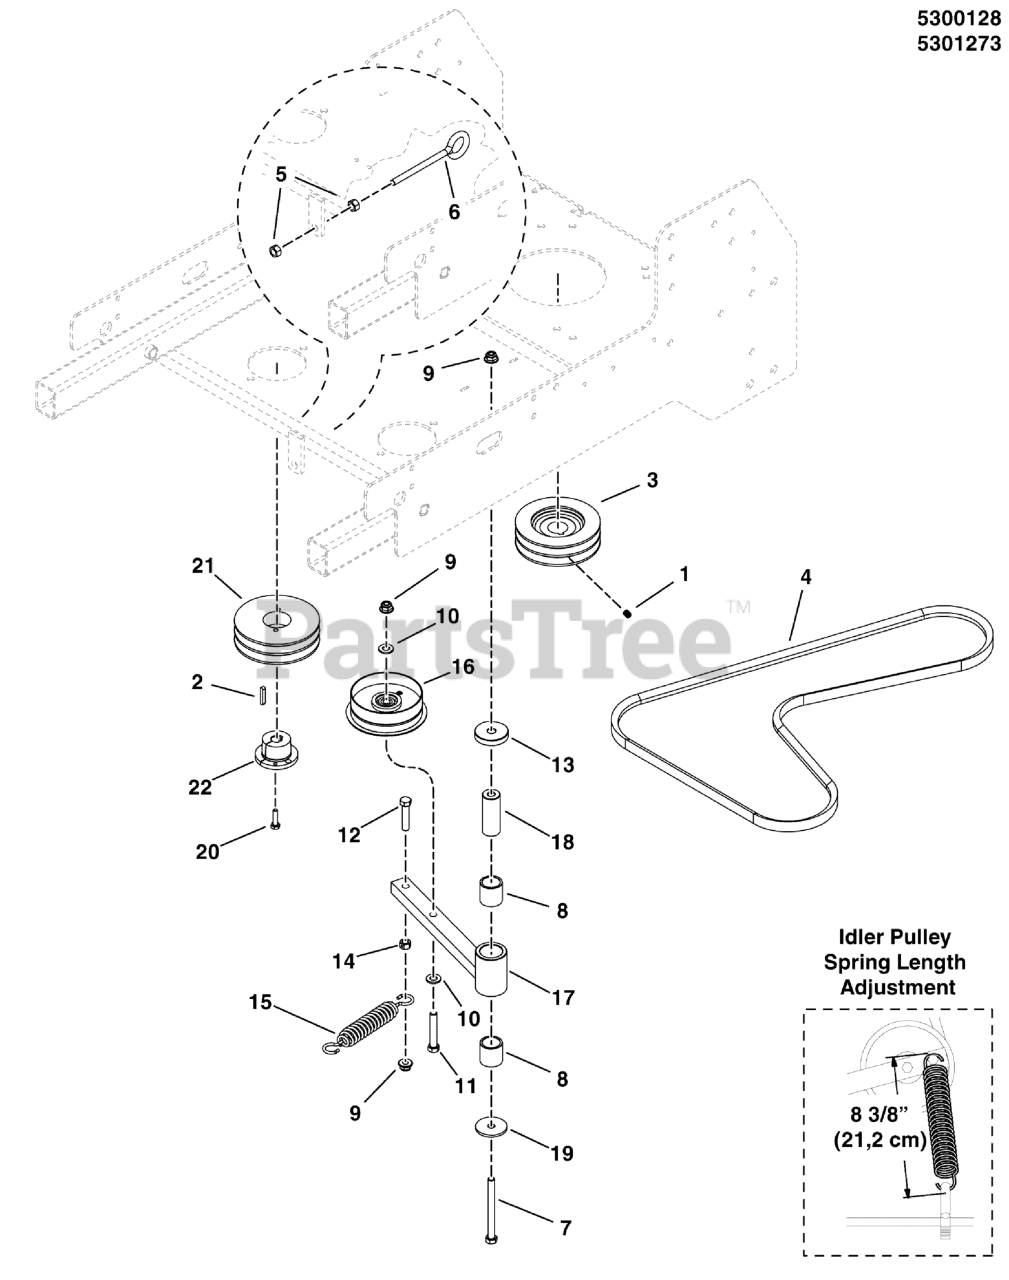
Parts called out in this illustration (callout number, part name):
1	SET SCREW, 5/16-18 X 3/8, KNURL, W/PATCH
2	KEY, 5MM SQ. W/ RADIUS
3	CRANKSHAFT PULLEY
4	BELT, BANDED A-SEC,64.76EL,POLY,RAW EDGE
5	NUT, 3/8-16 HEX
6	EYE BOLT, 3/8-16 X 6, 3.0 THREAD
7	BOLT, 3/8-16 X 4" GD5 CZ
8	BUSHING, BRASS, 1.25X1X1.25
9	NUT, 3/8-16 HEX NYLOCK FLANGE
10	WASHER, 3/8 GD.9 FLAT
11	BOLT, 3/8-16 X 2-1/4" GD5 CZ
12	BOLT, 3/8-16 X 1-3/4" GD5 CZ
13	SPACER, .45 X 1.88 X .38
14	NUT, 3/8-16 HEX SIDE LOCK
15	SPRING-EXT, 1.04 ODX6.935LGX.148WR, BLK
16	PULLEY, IDLER, SINGLE FLANGE
17	See "PUMP DRIVE [Cast Idler Arm for replacing Steel Pump Drive Idler Arm]"
18	SPACER, .39 X 1.00 X 2.55, SS
19	WASHER, .41 X 1.75 X .14
20	BOLT, 1/4-20 X 1" GD5 CZ
21	PULLEY, PUMP DRIVE
22	BUSHING, TAPERED HUB
